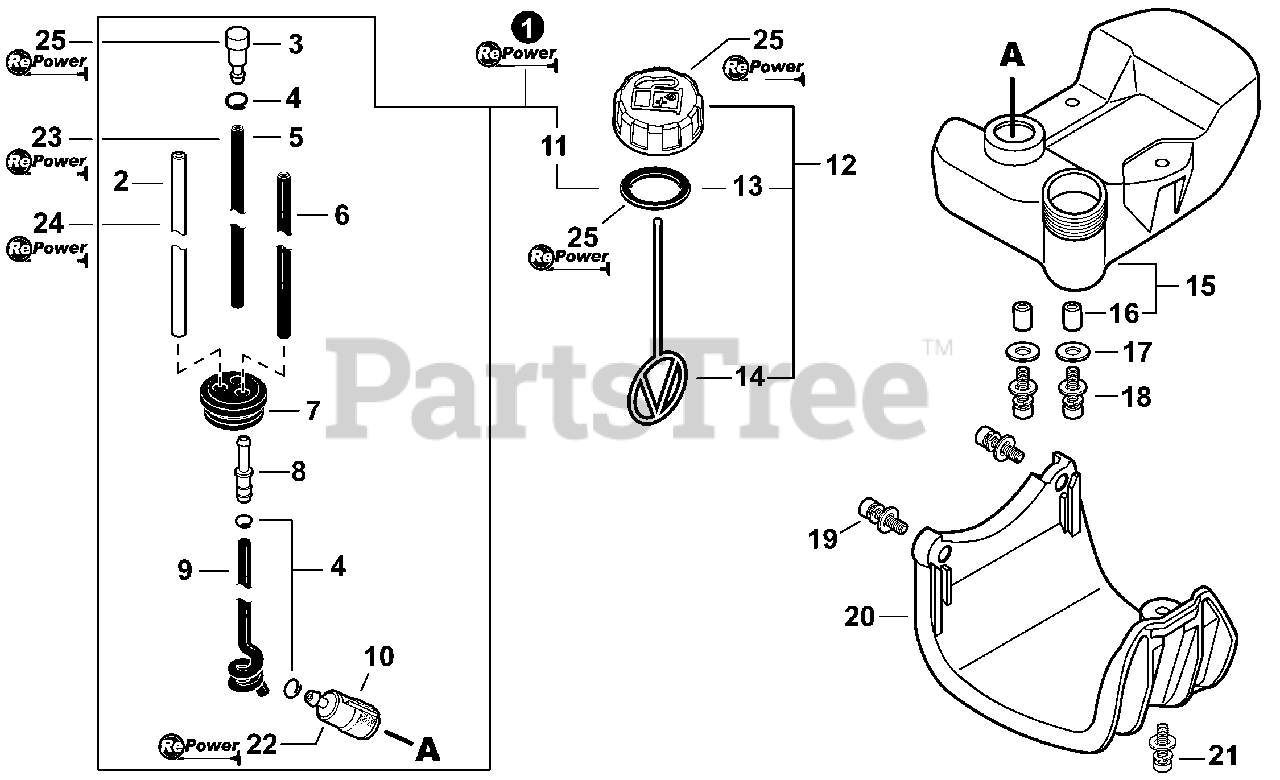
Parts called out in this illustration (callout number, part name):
1	FUEL SYSTEM KIT
2	PIPE, FUEL 3×6×80 CLEAR
3	VENT ASSY
4	CLIP Ø6.5 MM
5	PIPE 3×6×115 BLACK
6	PIPE, FUEL 3×5×74 BLACK
7	GROMMET, FUEL
8	CONNECTOR, PIPE Ø5ר3.5
9	PIPE, FUEL 3×6×105
10	FILTER, FUEL
11	GASKET, FUEL CAP
12	CAP ASSY, FUEL
13	GASKET, FUEL CAP
14	CONNECTOR, CAP L= 100 MM
15	TANK, FUEL
16	SPACER 6.2×7.8×6
17	WASHER 5.5×12×0.8
18	BOLT 5×16
19	BOLT 5×22
20	GUARD, FUEL TANK
21	SCREW 5×20
22	TUNE-UP KIT - REPOWER
23	BULK PIPE - 3×6 MM BLACK (4 PIECES×2 M)
24	BULK PIPE - 3×6 MM CLEAR (4 PIECES×2 M)
25	CAP/VENT KIT - REPOWER
